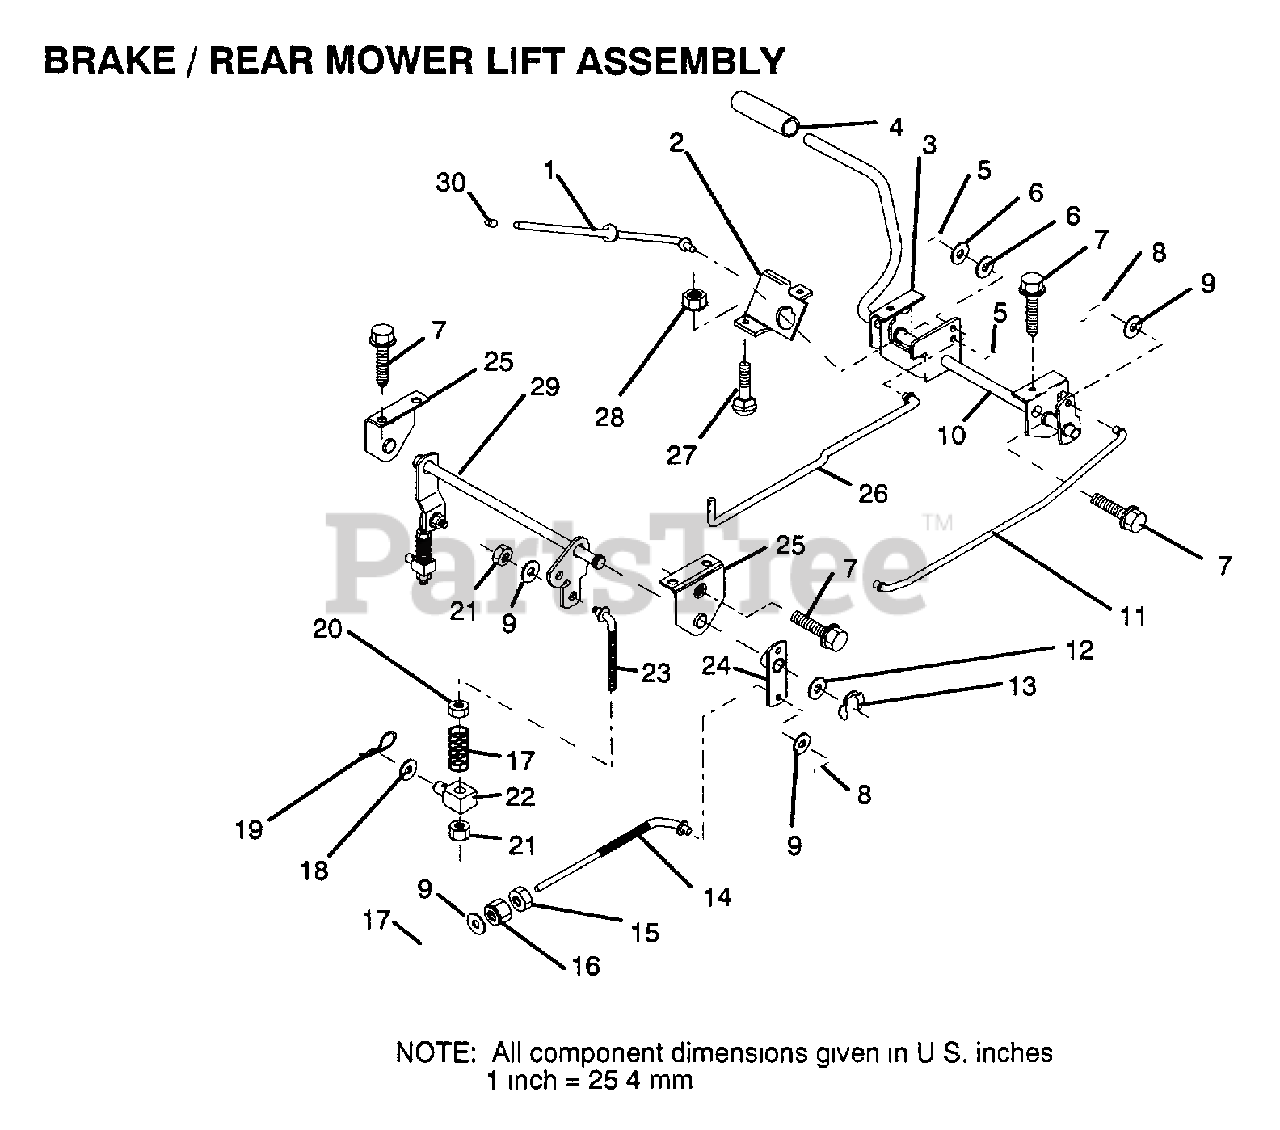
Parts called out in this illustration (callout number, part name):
1	"ROD,PARK BRAKE"
2	"BRKT,PARK BRAKE"
3	"BRKT,CLU PEDAL LH"
4	PEDAL COVER T
6	WASHER
7	SCREW LT
8	COTTER PIN
9	WASHER
11	"ROD,FRT BRAKE"
12	WASHER T
13	KLIP RING
15	NUT
16	NUT
17	SPRING ROD LT
18	WASHER
19	SPRING.RETAINER
20	LOCKNUT
23	"LINK.LIFT.3.5"""
24	BRAKE PIVOT ARM
25	"BRKT,LIFT SHAFT"
26	"ROD,CLUTCH"
29	REAR MOWER LIFT
30	PLUNGER CAP T
